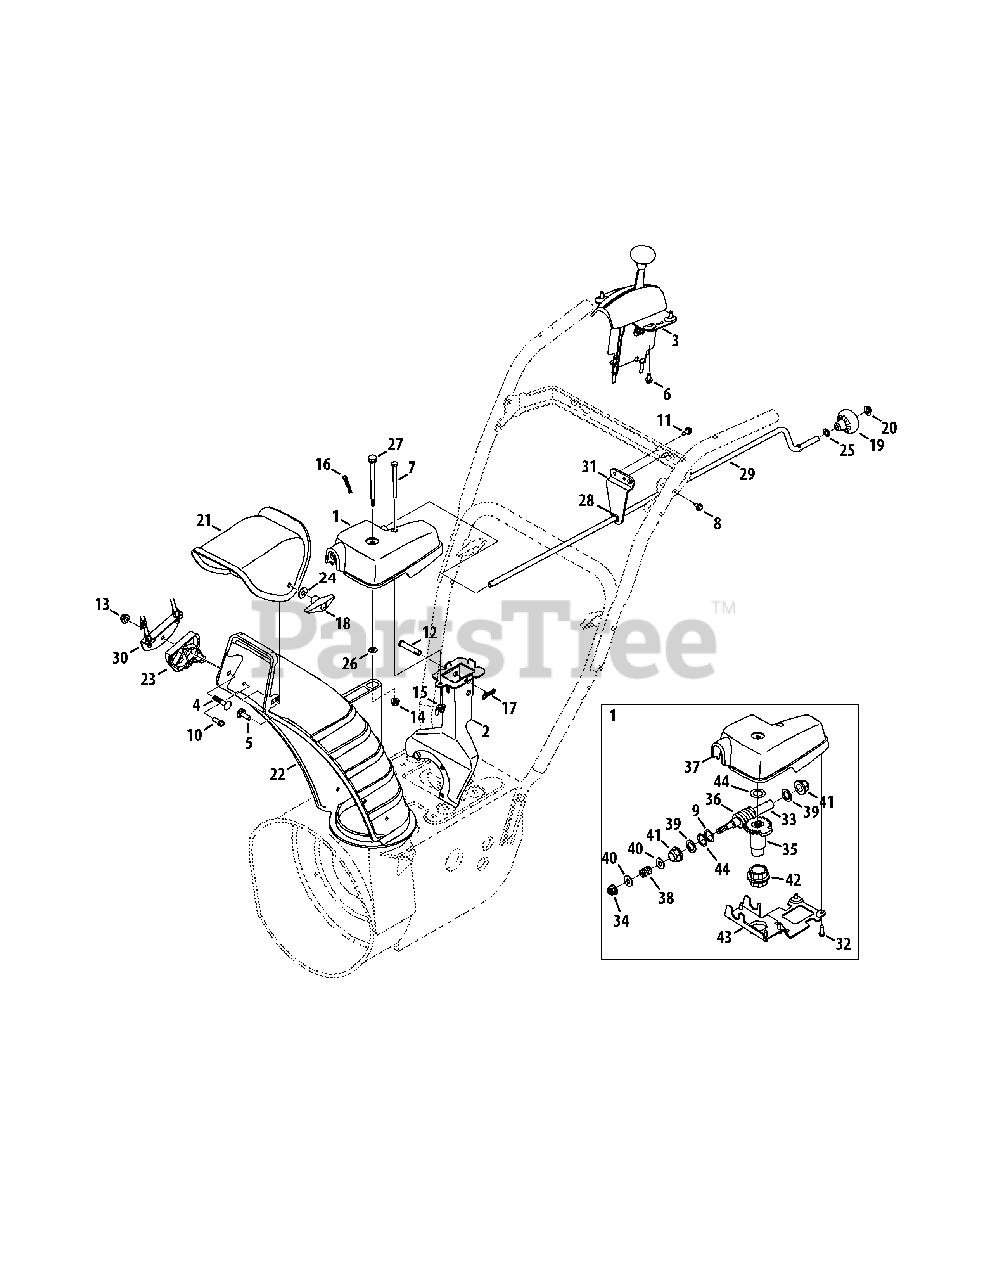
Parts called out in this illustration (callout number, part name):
1	Chute Rotation Gearbox
2	Chute Support Bracket
3	Chute Control, 2-Way
4	Bolt, Carriage, 5/16-18 x 1.50
5	Bolt, Carrier, 5/16-18 x 1.00
6	Screw, Hi-Lo, 1/4-15 x 0.50
7	Hex Head Screw, 1/4-20 x 3.00
8	Screw, TT, 1/4-20 x .500
9	Shim Washer, .632 x 1.00 x .010
10	Screw, Hi-Lo, 1/4-15 x 0.750
11	Screw, 1/4-20 x .625
12	Clevis Pin, 3/8 x 1.87
13	Nut, Flange Lock, 5/16-18
14	Nut, Flange Lock, 1/4-20
15	Wing Nut, 1/4-20
16	Internal Cotter Pin
17	Bow-Tie Cotter Pin
18	Wing Knob, 5/16-18
19	Shift Knob, .390
20	Push Cap, 3/8
21	Upper Chute
22	Lower Chute, 5.0
23	Cable Guide, Chute Tilt
24	Washer, Flat, .349 x .879
25	Flat Washer, .375 x .738 x .063
26	Washer, Flat, .25 x .630
27	Shoulder Screw, .312 x 3.5 x 1/4-20
28	Plastic Bushing, .380 ID
29	Chute Crank
30	Cable Bracket
31	Support Rod Bracket
32	Screw, 12-16 x .75
34	Flange Lock Nut, 3/8-16
35	Gear Assembly
36	Worm
38	Compression Spring, .39 x .60 x .88
39	Flat Washer, .625 x 1.0 x .067
40	Flat Washer, .380 x .93 x .110
41	Hex Bearing
42	Flange Bearing
44	Shim Washer, .63 x 1.00 x .020
